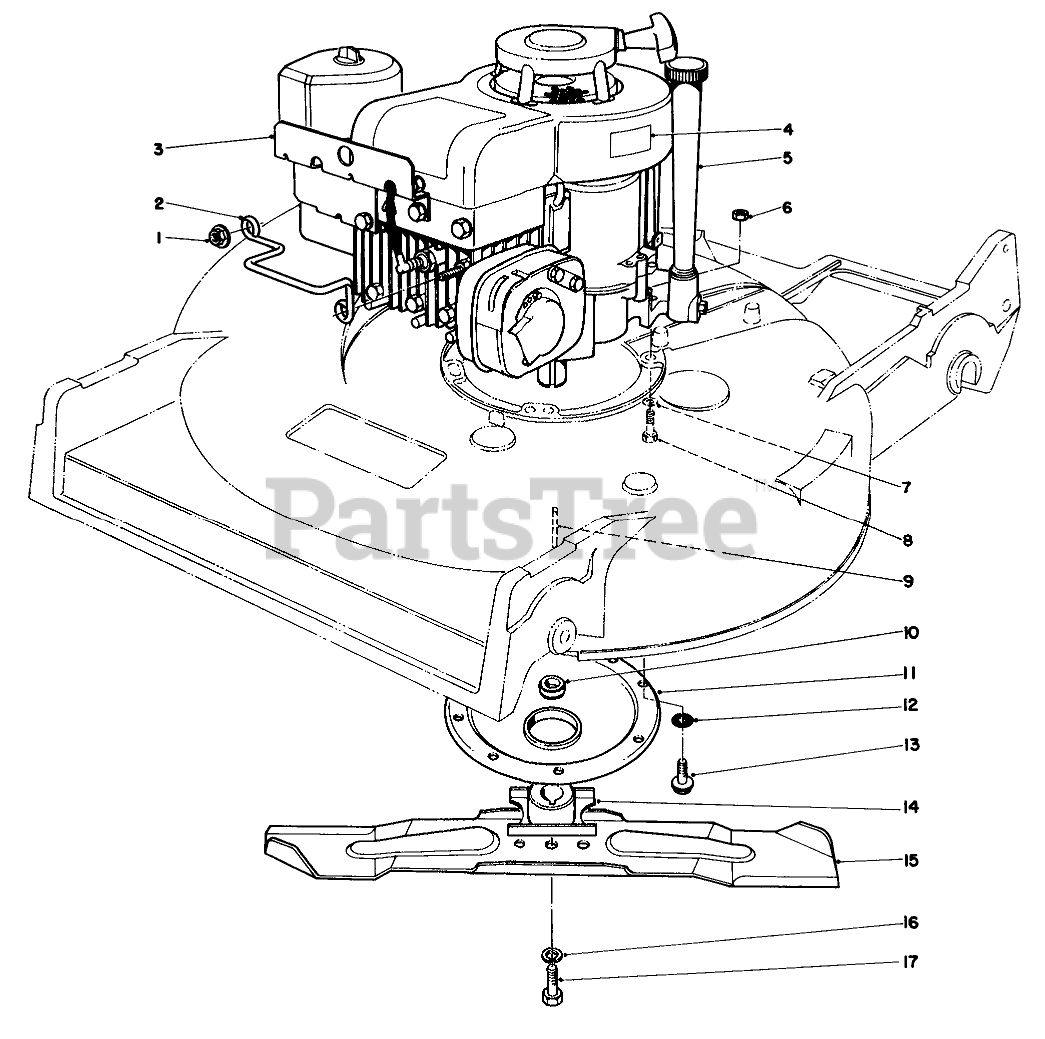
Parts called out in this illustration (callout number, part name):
1	NUT-HF
2	Protector-Spark Plug
3	ENGINE GD BRKT
4	Decal-Oil Caution
5	Engine
6	NUT-LOCK, CONE
7	WASHER-PLAIN
8	SCREW-HH
10	BLADE RETAINER SPACER
11	PROTECTOR-CRANKSHAFT
12	WASHER-LOCK, INTERNAL
13	SCREW-HWHTF
14	BLADE RETAINER W A
15	BLADE-21in
16	WASHER-LOCK
17	BLADE SCREW
